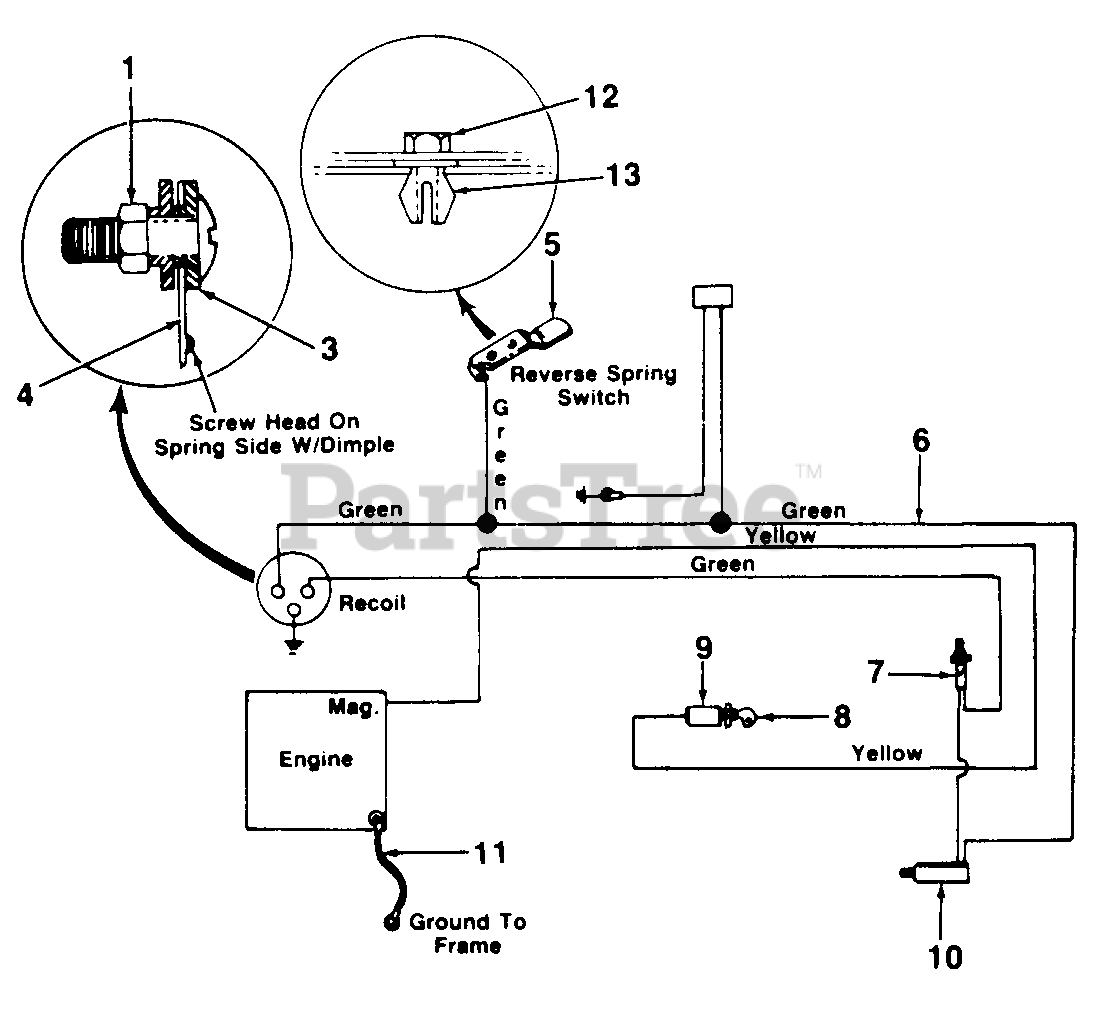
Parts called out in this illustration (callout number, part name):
1	Hex Nut #10-24 Thd.*
3	Fiber Washer
4	Switch Spring-Recoil
5	Spring Switch-Reverse
6	Wire Harness
7	Safety Switch-Red N.C.-Clutch
8	Ignition Key
9	Ignition Switch
10	Safety Switch P.T.O.
11	Ground Wire
12	Truss Mach. Scr. #10-24
13	Push-In Nut #10
